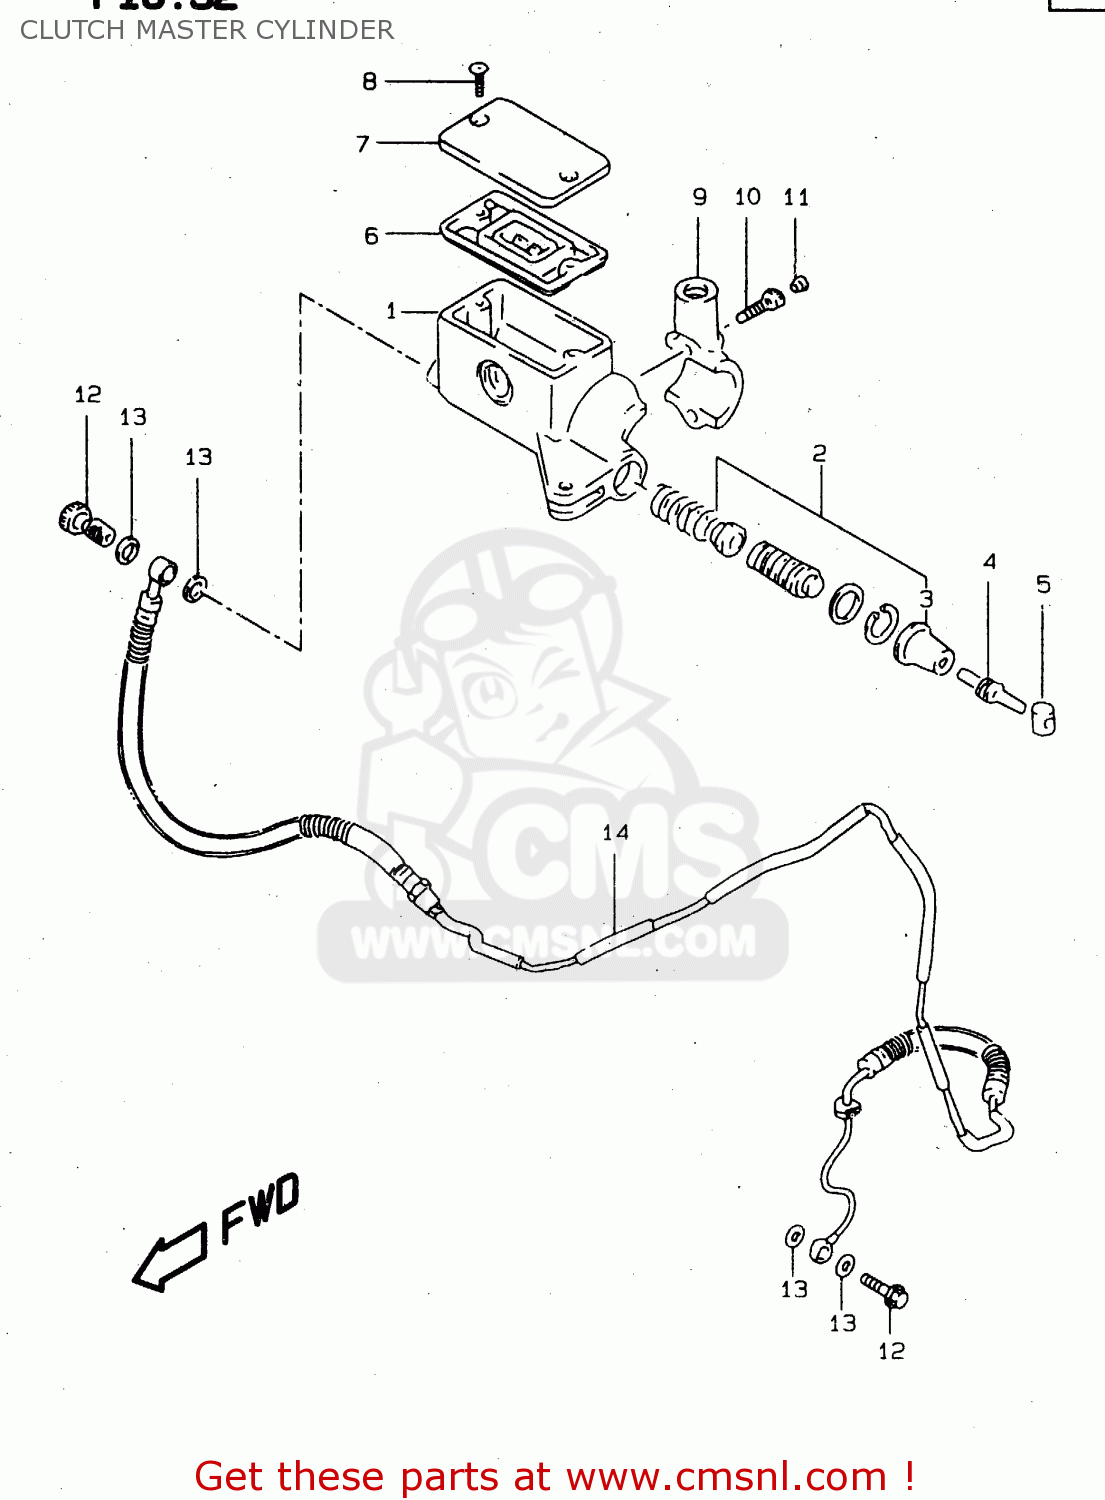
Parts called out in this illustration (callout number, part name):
1	CYLINDER ASSEMBLY,CLUTCH MASTER
2	PISTON & CUP SET
3	BOOT
4	PUSH ROD
5	BUSH
6	7
7	CAP
8	SCREW
9	HOLDER
10	BOLT
11	CAP(OD:10)
12	BOLT UNION
13	WASHER(10X15X1.5)
14	HOSE ASSY,CLUTCH
